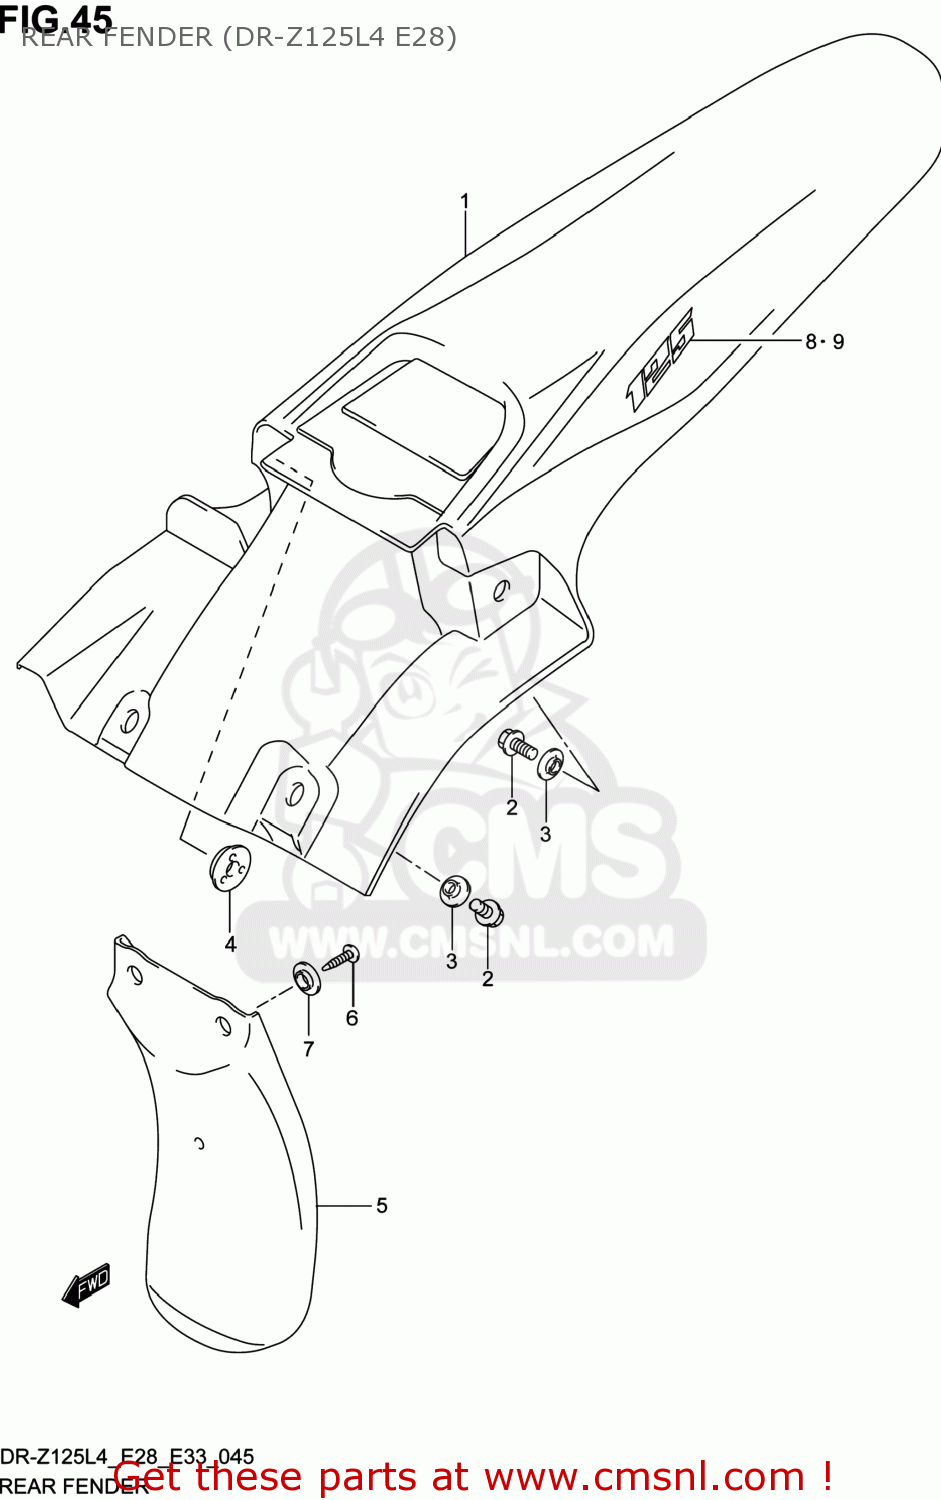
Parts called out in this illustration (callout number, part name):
1	FENDER,RR
2	BOLT(6X16)
3	WASHER
4	WASHER
5	MUDGUARD,RR FENDER FR
6	SCREW(5X16)
7	WASHER
8	EMBLEM,125,R
9	EMBLEM,125,L
